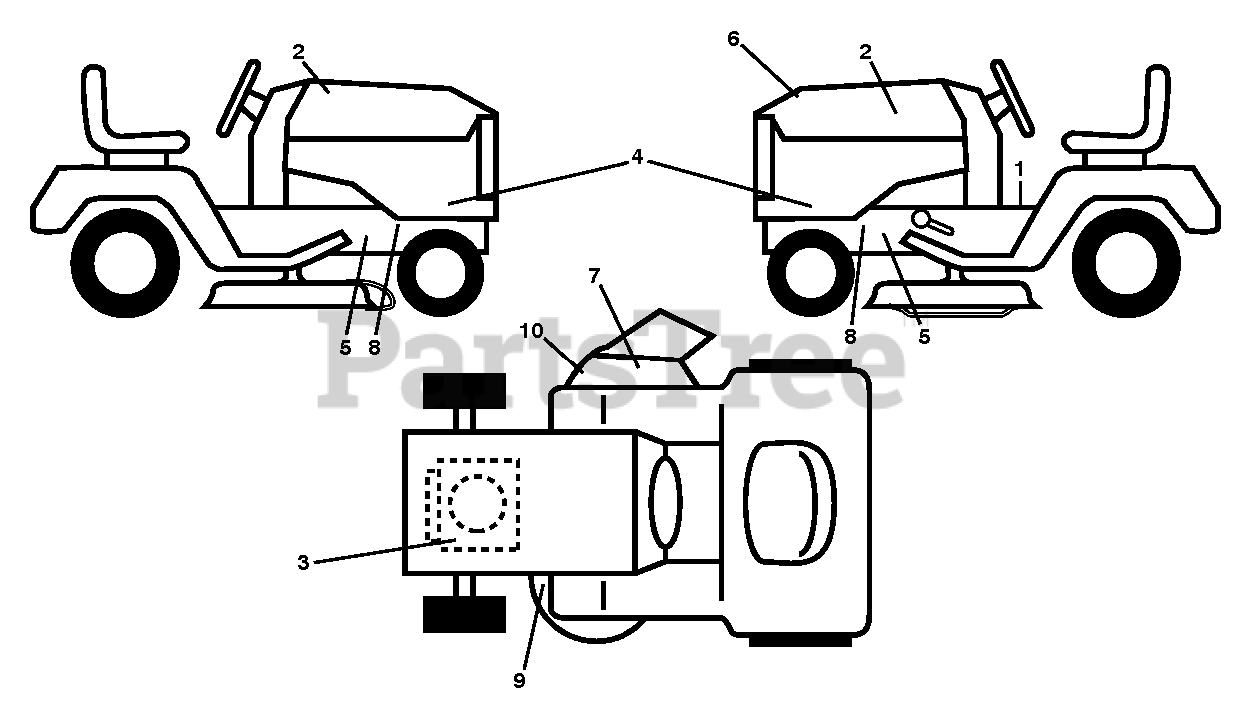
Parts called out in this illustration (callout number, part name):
1	DECAL.TRACTOR.SADDLE
2	DECAL.WB.178MM.15.HUSQ.NEWBRAN
3	DECAL.ENGINE.WARNING
5	DECAL.WARNING.HOT.MUFFLER.2021
7	DECAL.DECK.DEFLECTOR.WARNING
8	DECAL.WARNING.SERVCE/FIRE
10	DECAL.DFLCTR.WARNNG.CTFNGR.SYM
